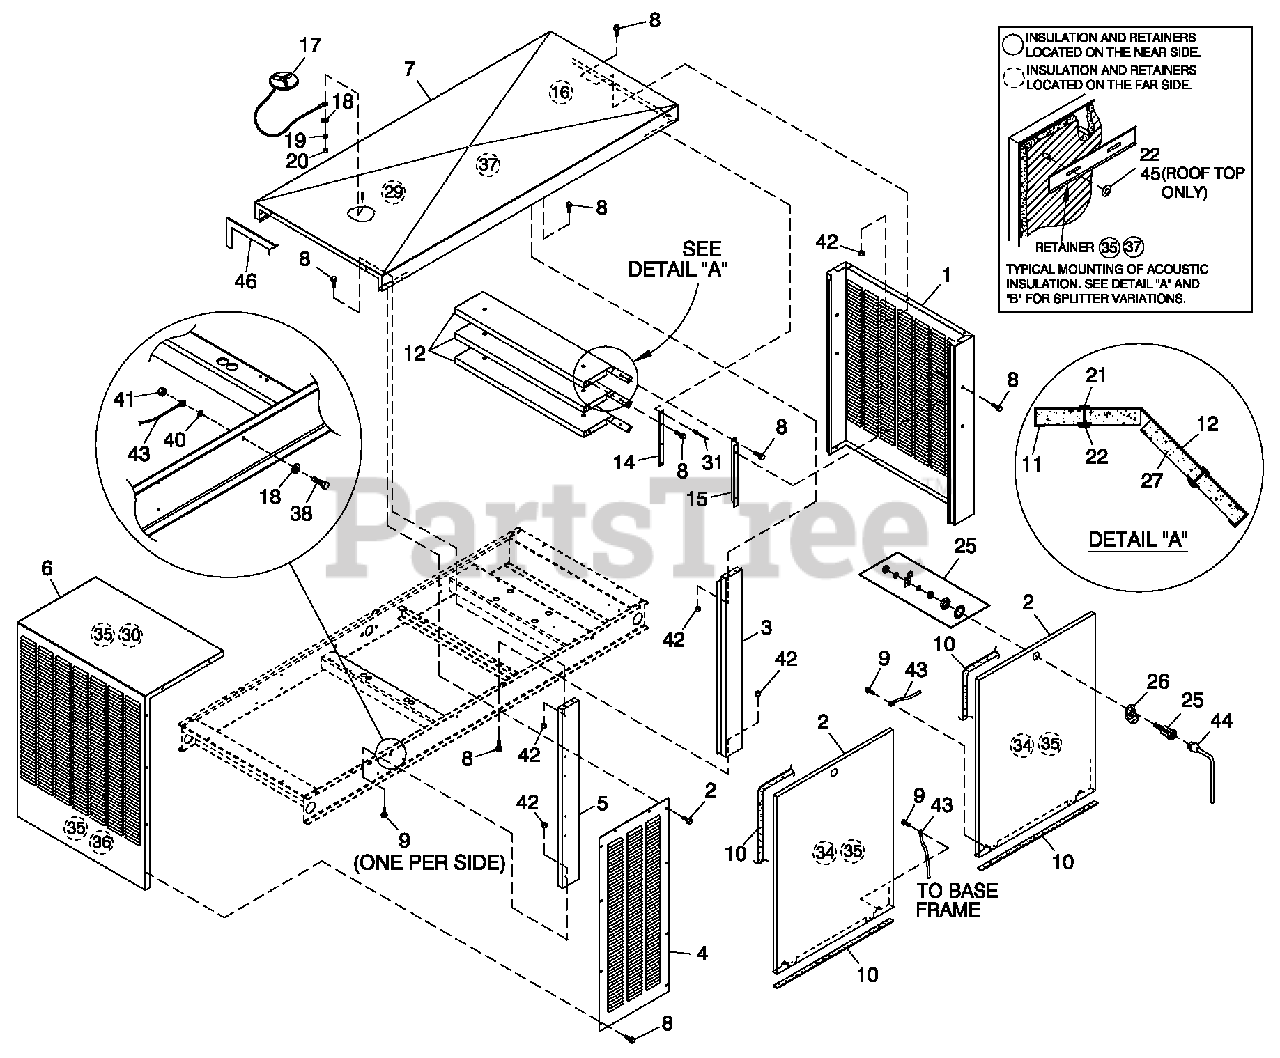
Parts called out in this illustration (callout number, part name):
1	REAR WRAP C3
2	DOOR C3
3	CENTER SUPPORT C3
4	DISCHARGE DUCT LH & RH SIDE C3
5	FRONT CORNERS C3
6	DISCHARGE CENTER DUCT C3
7	ROOF C3 ALUM
8	SCREW THF M6-1 X 16 N WA Z/JS
9	SCREW TH-FRM M6 W/CAP SHKPRF W
10	GASKET EXTRUDED TRIM (547" LG)
11	INSULATION SPLITTER SML
12	SPLITTER
14	STRINGER SPLITTER C3
15	SUPPORT SPLITTER C5 130KW
16	INSULATION ROOFTOP REAR
17	ASSEMBLY COVER ACCESS
18	WASHER FLAT 1/4-M6 ZINC
19	WASHER LOCK M6-1/4
20	NUT HEX 1/4-20 STEEL
21	INSULATION RETAINMENT HANGER
22	WASHER SELF LOCKING DOME #4-40
25	VISE-ACTION LATCH SLOTTED CIR
26	TAB PULL
27	INSULATION SPLITTER
29	INSULATION ROOFTOP
30	INSULATION DUCT TOP
31	RIVET POP .1875 X .450 SS
32	SPLITTER EXTENDED LENGTH
33	INSULATION SPLITTER EXTENDED LENGTH
34	INSULATION DOOR
35	RETAINER INSULATION (820)
36	INSULATION DUCT FRONT
37	RETAINER INSULATION (740)
38	SCREW HHC M6-1.0X20G8.8
40	WASHER SHAKEPROOFINT1/4
41	NUT H E XM6X1 .0G 8YEL CHR
42	NUT HEX LOCK M6-1.0 SS NY INS
43	ASSY WIRE 14 AWG 34.8" GRN/YEL
44	KEY VISE-ACTION LATCH SLOT CIR
45	WASHER SELF LOCKING DOME #8-32
46	STRIP SEALANT 1/8 X 1 (44.52"LG)
